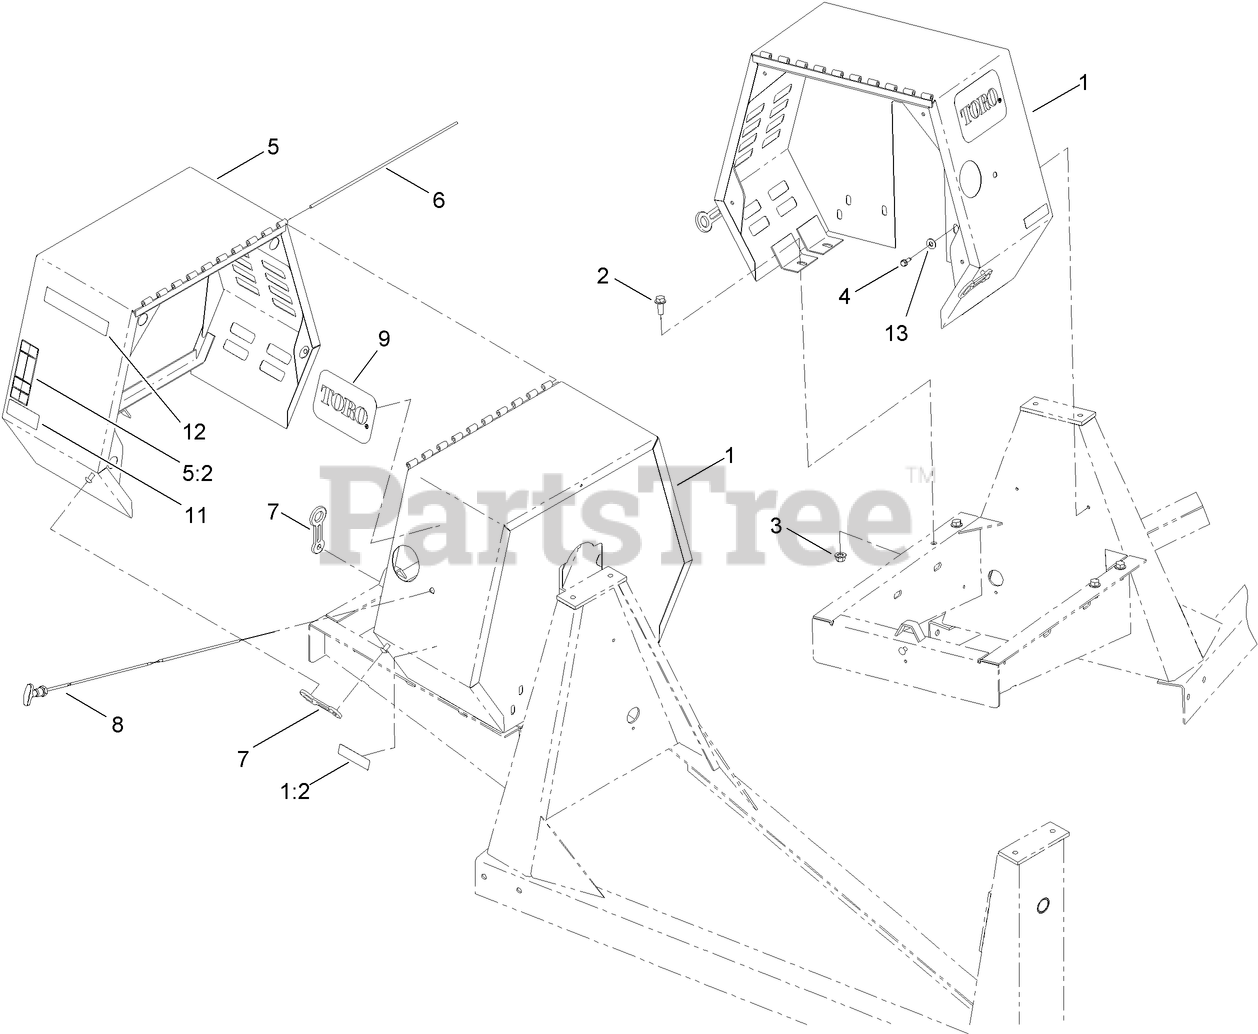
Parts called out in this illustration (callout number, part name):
1	STATIONARY COWL ASM
1:2	DECAL-ARRESTER, SPARK
2	SCREW-HHF
3	NUT-LOCK
4	SCREW-HWHTF
5	MOVABLE COWL ASM
5:2	DECAL-WARNING
7	LATCH-RUBBER
8	CABLE-THROTTLE
9	DECAL
13	WASHER-FLAT
